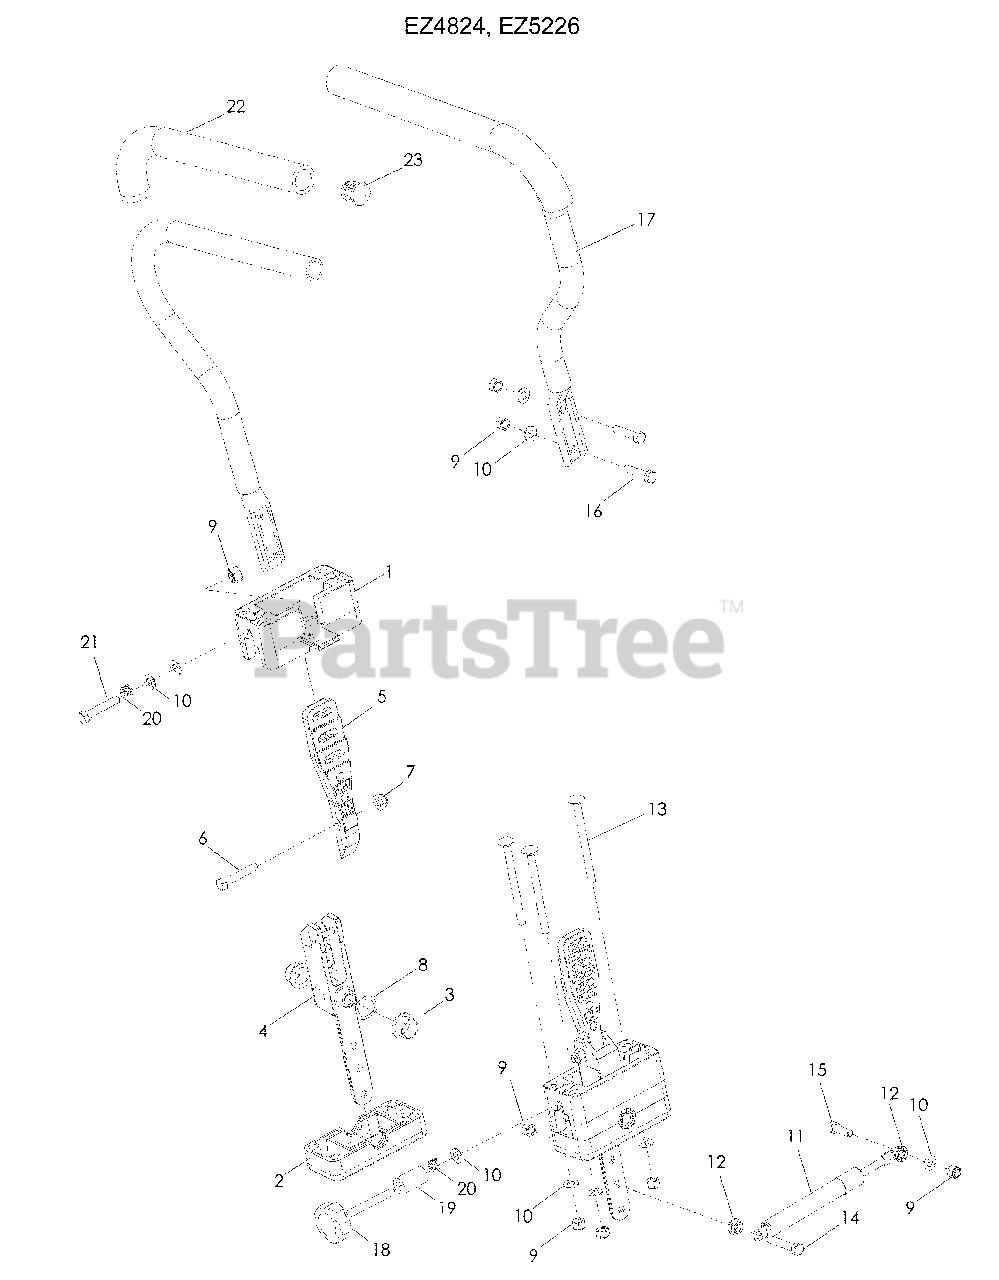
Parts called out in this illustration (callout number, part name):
1	BLOCK, UPPER
2	BLOCK, LOWER
3	BEARING, FLANGE
4	PIVOT SECTION, DRIVE
5	MOUNT, DRIVE CONTROL
6	HCS 5/16-18 x 1¾
7	NUT 5/16-18 FLANGE NYLOC
8	WASHER, .825 x 1.087 WAVE
9	NUT 5/16-18 HEX NYLOC
10	WASHER 5/16 SAE FLAT
12	NUT 5/16-18 HEX WHIZLK
13	RHSNB 5/16-18 x 4
14	HCS 5/16-18 x 1¾ TPBLT
15	HCS 5/16-18 x 1
16	HCS 5/16-18 x 1½
17	LEVER, w/GRIP
21	HCS 5/16-18 x 2 TPBLT
22	GRIP, FOAM
